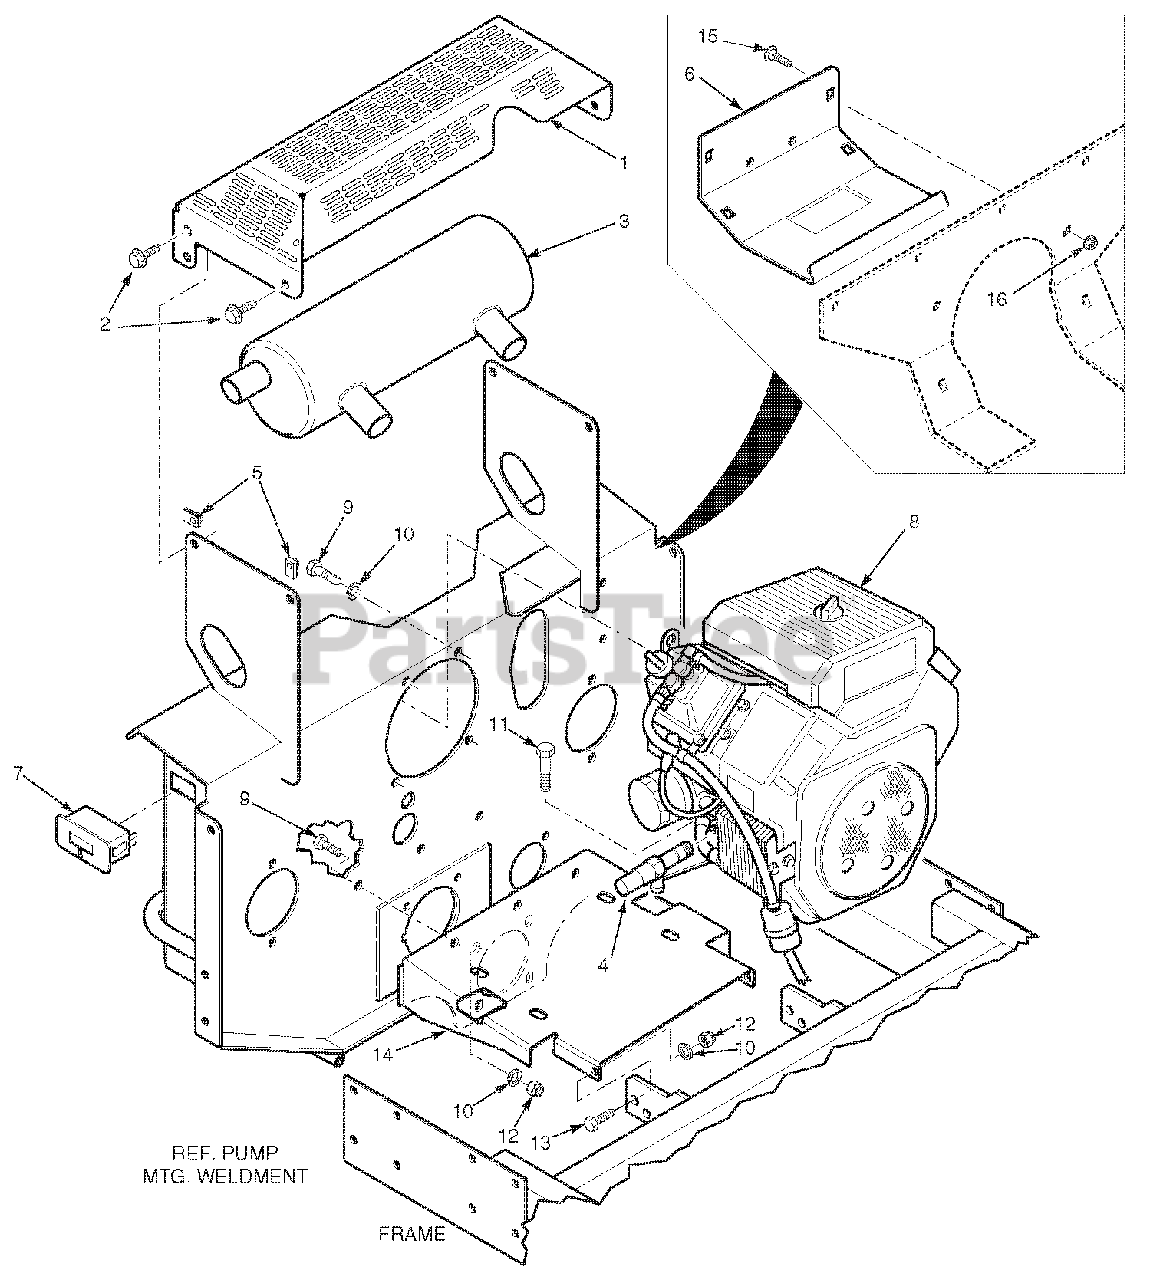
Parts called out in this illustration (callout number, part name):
1	Muffler Guard
2	Screw, Hex Serrated Flange 1/4-20 x 3/4"
3	Muffler, Part Of Engine
4	Oil Drain Extension
5	U-Nut, 1/4-20
6	Rear Cover
7	Hour Meter, Inductive
8	Engine, Kohler 25 CH LP
9	Bolt, Hex Head 3/8-16 x 1"
10	Lockwasher, 3/8" Spring
11	Bolt, Hex Head 3/8-16 x 1-3/4"
12	Nut, Hex Elastic Stop 3/8-16
13	Bolt, Hex Head 3/8-16 x 1-1/4"
14	Plate, Engine Mounting
15	Bolt, Carriage 5/16-18 x 3/4"
16	Nut, Hex Serrated Flange 5/16-18
